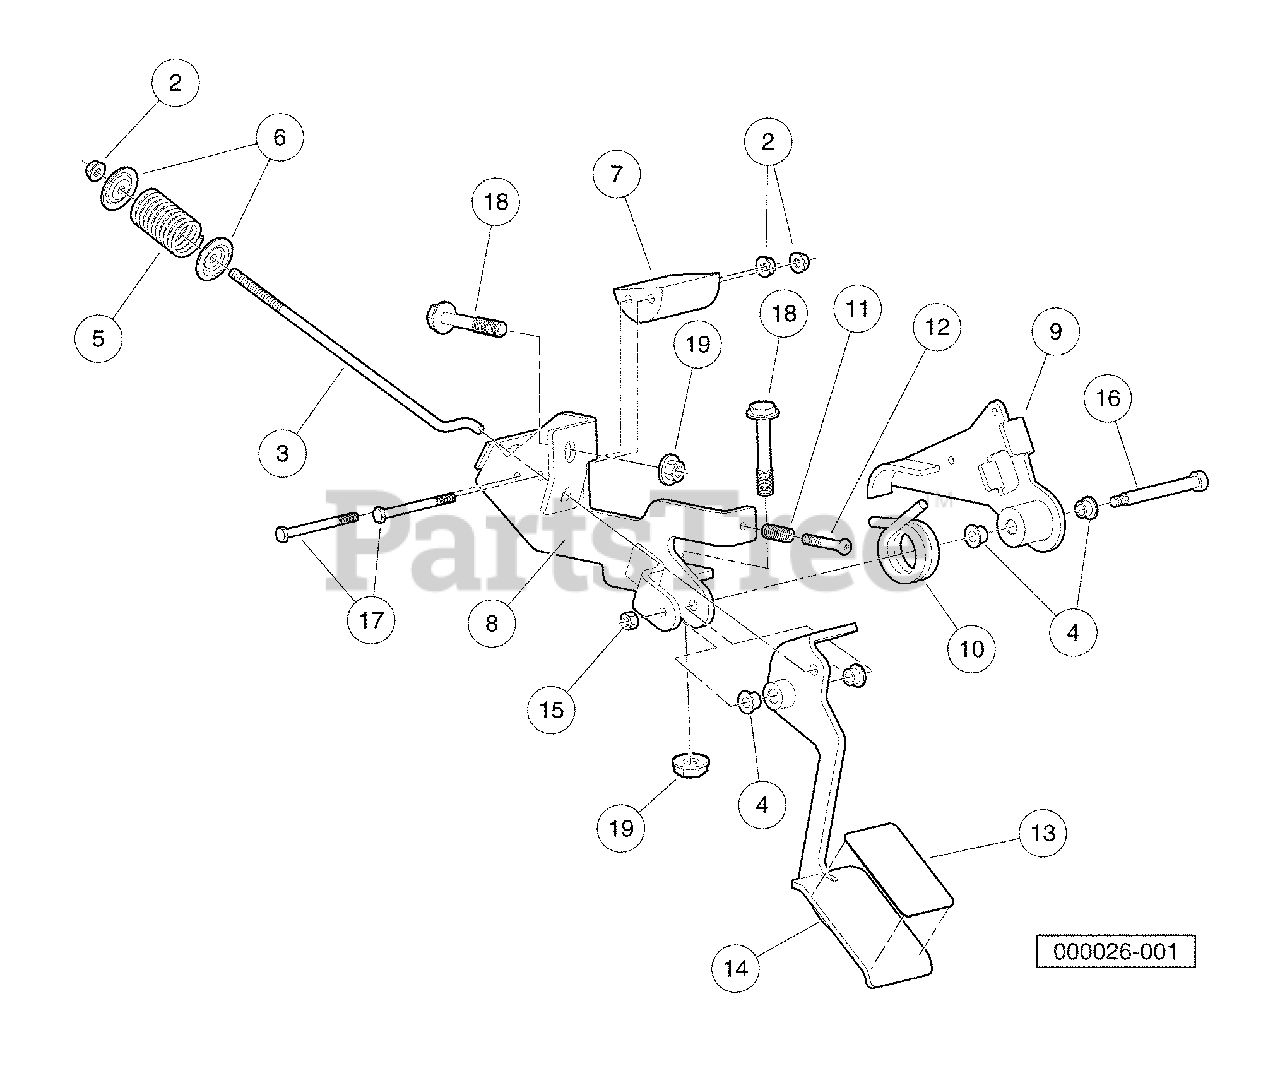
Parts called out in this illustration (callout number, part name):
1	Asm, Pedal, Accelerator
2	Nut-m6x1.0 Flng All Mtl Lock
3	Pullrod, Spring, Compression
4	Bushing, Greaseless
5	Spring, Comp, Pedal, Pullrod
7	Guide, Cable, Accelerator
8	Weldment, Bracket, Pedal
9	Weldment, Lever, Motion, Lost
10	Spring, Torsion
11	Spring, Stop, Pedal
12	Bolt, Stop, Pedal
13	Pad, Grip Tape, Accelerator
14	Weldment, Pedal, Accelerator
15	Nut M6x1 Mech Def Center
16	Bolt, Shoulder, M8 X 70, Hc
17	Bolt, M6 X 1 X 70
18	Bolt Flanged Head, M8 X 1.25 X 65
19	Lock Nut, Flg M8 X 1.25 Nylon
